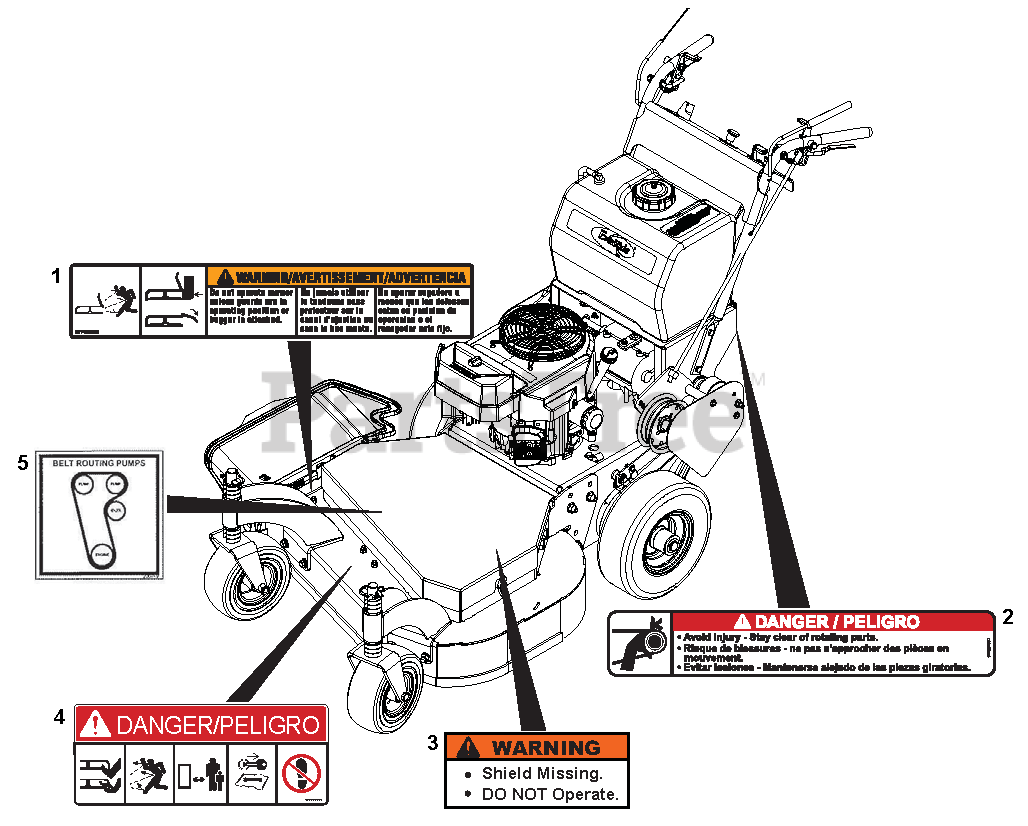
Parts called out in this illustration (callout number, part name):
1	DECAL, WARNING
2	DECAL-DANGER-BELT ROTATING
3	DECAL, WARNING - SHIELD
4	DECAL, MOWER PAN DANGER
5	DECAL, DECK BELT ROUTING
